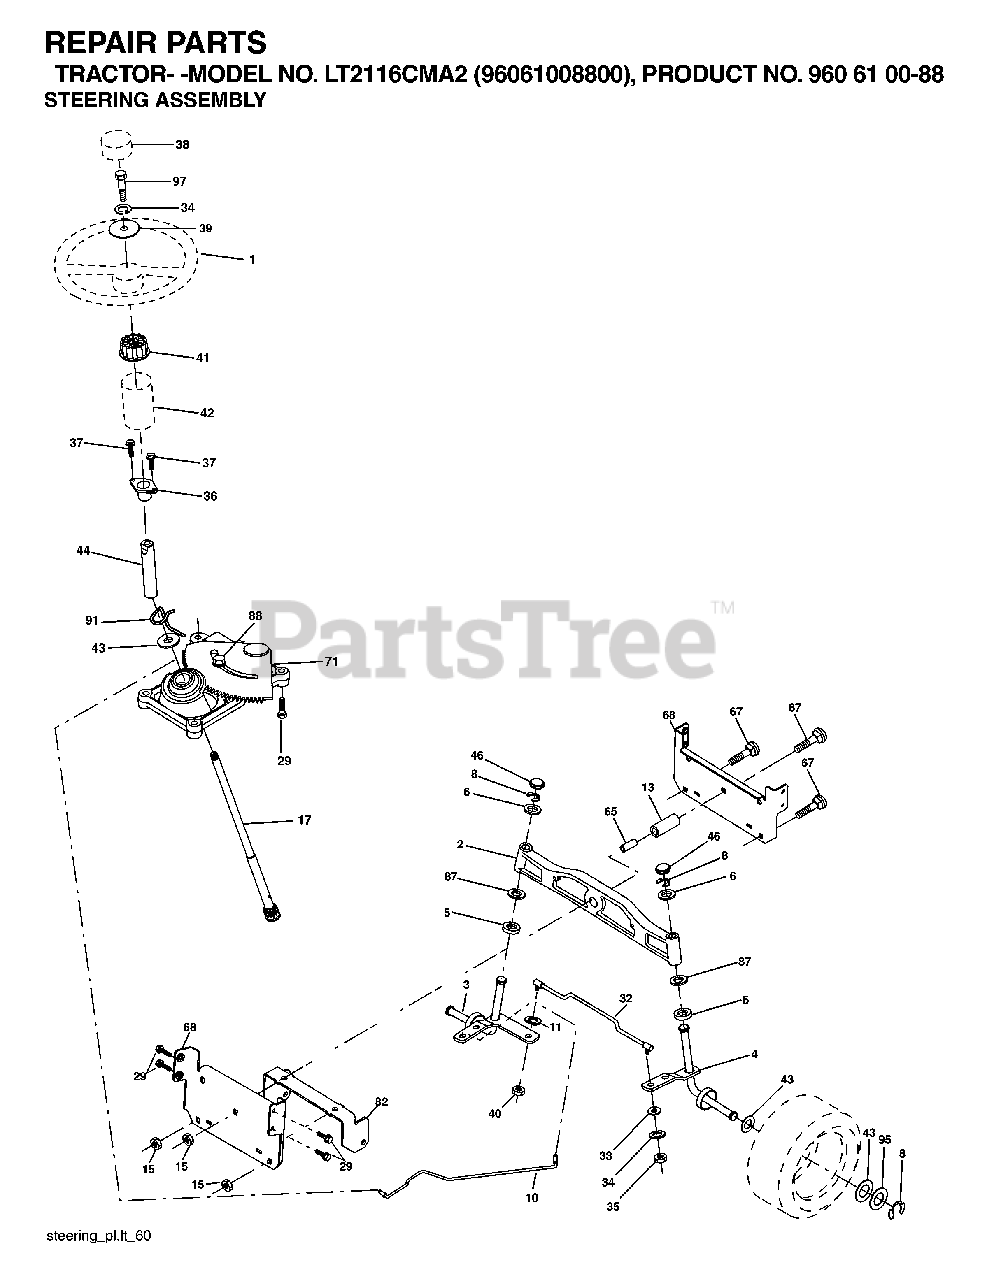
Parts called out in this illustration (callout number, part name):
1	WHEEL.STEERING.PREM.2.BLK
2	AXLE ASSY FRONT
3	SPINDLE.ASM.LH.15"TIRES
4	SPINDLE.ASM.RH.15"TIRES
8	RING CLIP
10	DRAGLINK.15".TIRES.2001
11	WASHER, LOCK 3/8
13	TUBE, PIVOT AXLE
15	NUT
17	SHAFT STEERING SPLINE
29	SCREW, 3/8-16X3/4
32	ROD.ASM.TIE.BALL.JOINT.NOVAN
33	WASHER M
34	LOCKWASHER
35	NUT, CROWNLOCK
36	BUSHING, STEERING
38	INSERT.CAP.STRG.WH.BLACK
39	WASHER.11/32
40	NUT CROWNLOCK 3/8-24
41	ADAPTER, WHEEL STNG..
42	BOOT.STEERING.SHAFT.BLACK
44	SHAFT.EXTEN.STRG.SPLINE
46	CAP.SPINDLE
65	SPACER BRACE AXLE
67	BOLT CARRIAGE
68	BRACE.AXLE.15"TIRES
71	STEERING ASM
82	BRACKET.SUSP.CHASSIS.FRONT.15
87	WASHER, FLAT .781 X 1 1/2"
88	BOLT, SHOULDER 7/16-20
91	CLIP.STEERING
95	WASHER.HARDENED
